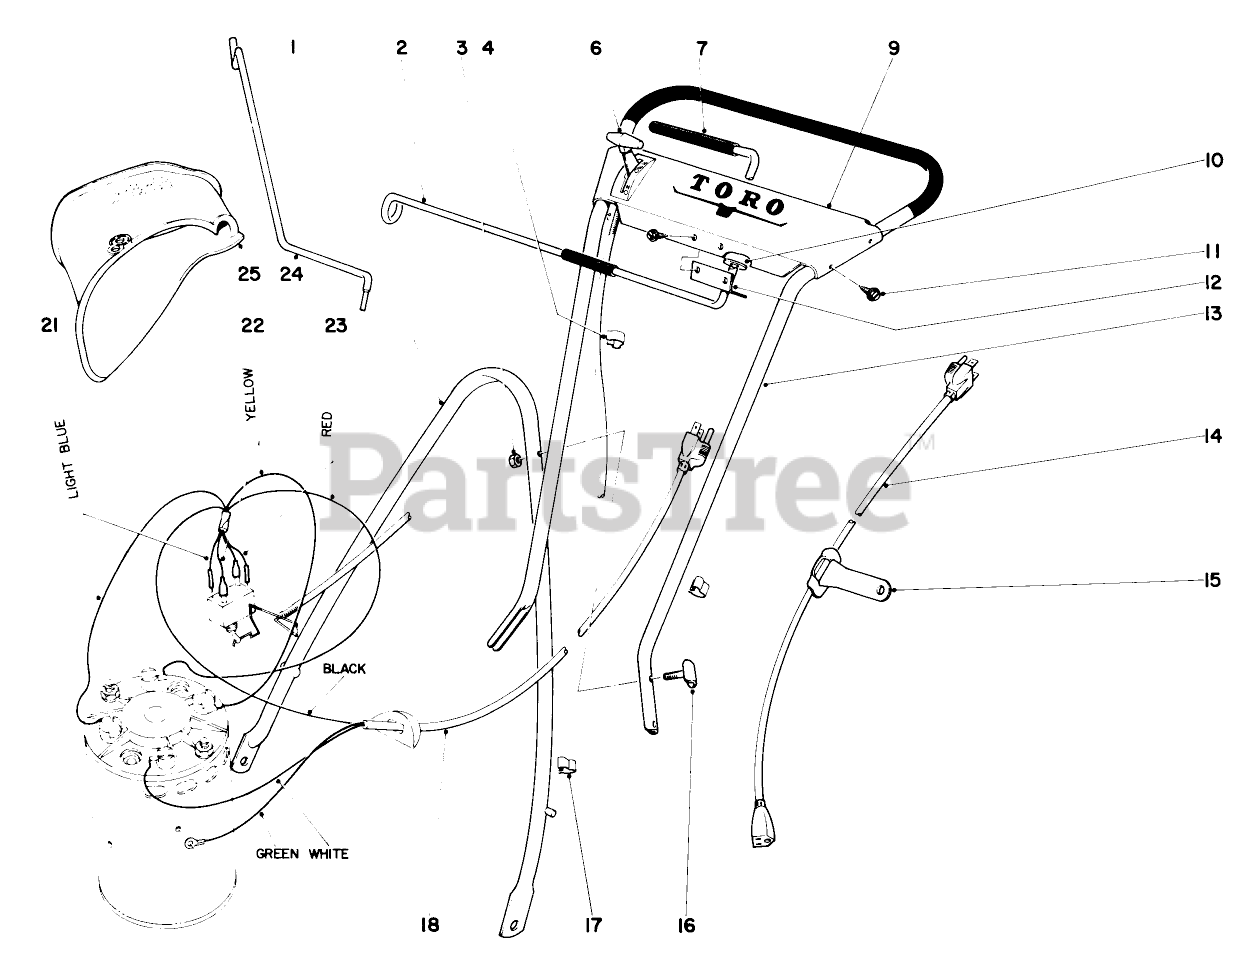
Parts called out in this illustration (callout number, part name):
1	Handle-Lower
2	Pivot Rod-Cord
3	Nut
4	CONTROL WIRE CLIP
6	Control-Switch
7	Grip-Pivot Rod
9	Plate-Escutcheon
10	WASHER-PLAIN
11	SCREW-HWHTF
12	Bracket-Escutcheon
13	Handle-Upper
14	Cord Assembly-100 ft. (Incl. Ref. No. 15)
14	Cord Assy.-100 ft. (Canadian)(Incl. Ref. No. 15)
15	Cord Strain Relief
18	Cord Assembly
18	Cord Assembly (Canadian)
21	Lead Wire (Blue)
22	Lead Wire (Yellow)
23	Lead Wire (Red)
24	GRASS BAG HANGER
25	Attachment Bag
